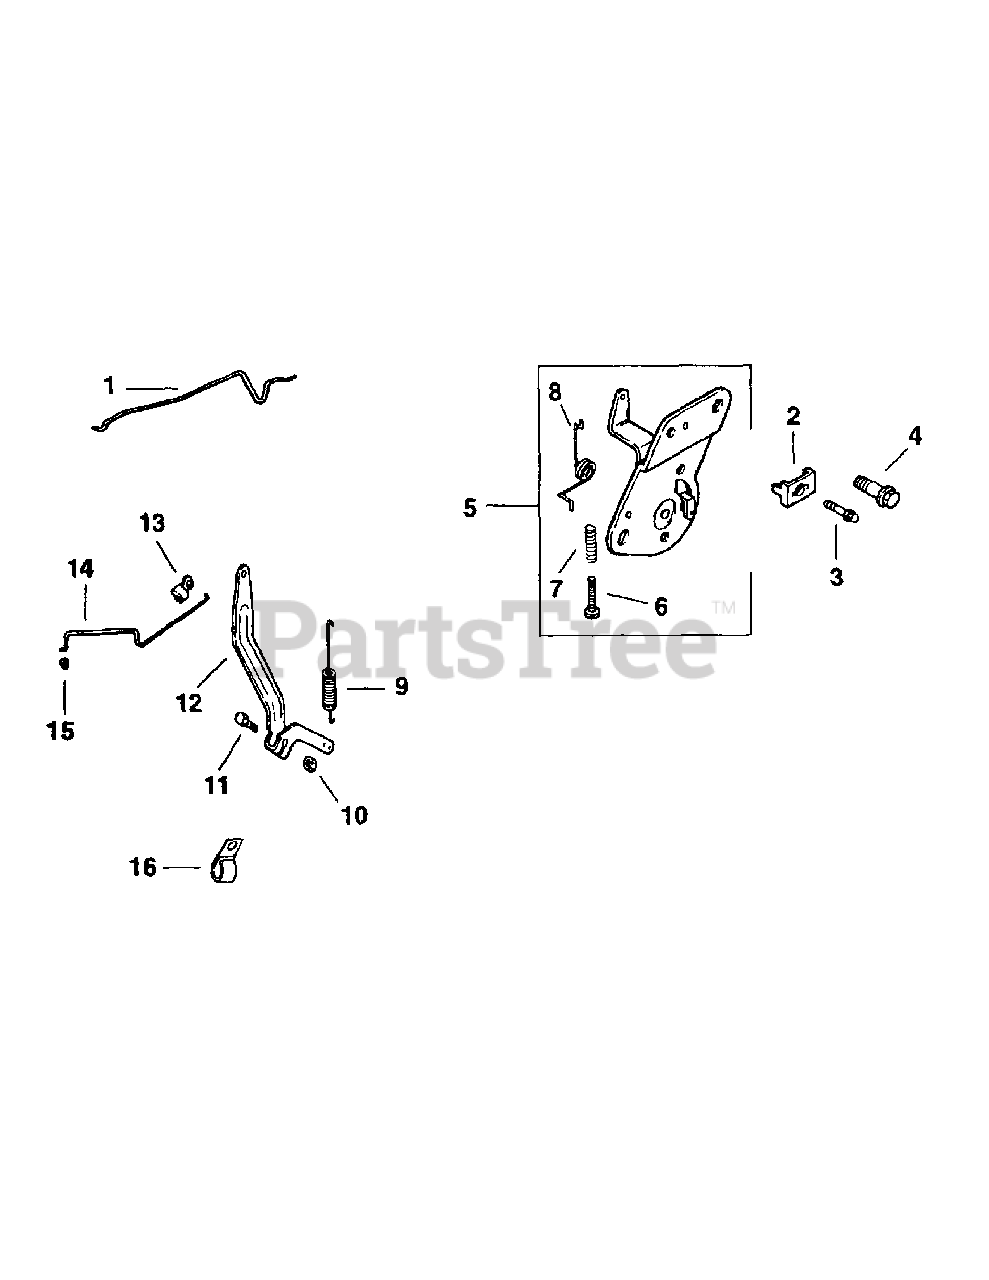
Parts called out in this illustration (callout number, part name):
1	Linkage, Choke
2	Clamp, Cable
3	Screw, Hex Flange
4	Screw, Hex Flange
5	Speed Control Assembly
6	Screw, Pan hd.
7	Spring, Choke
8	Spring, Choke Return
9	Spring, Governor
10	Nut, Hex Flange
11	Screw, Hex Cap
12	Lever, Governor
13	Bushing, Linkage Black
14	Linkage, Throttle
15	Bushing, Linkage Natural
